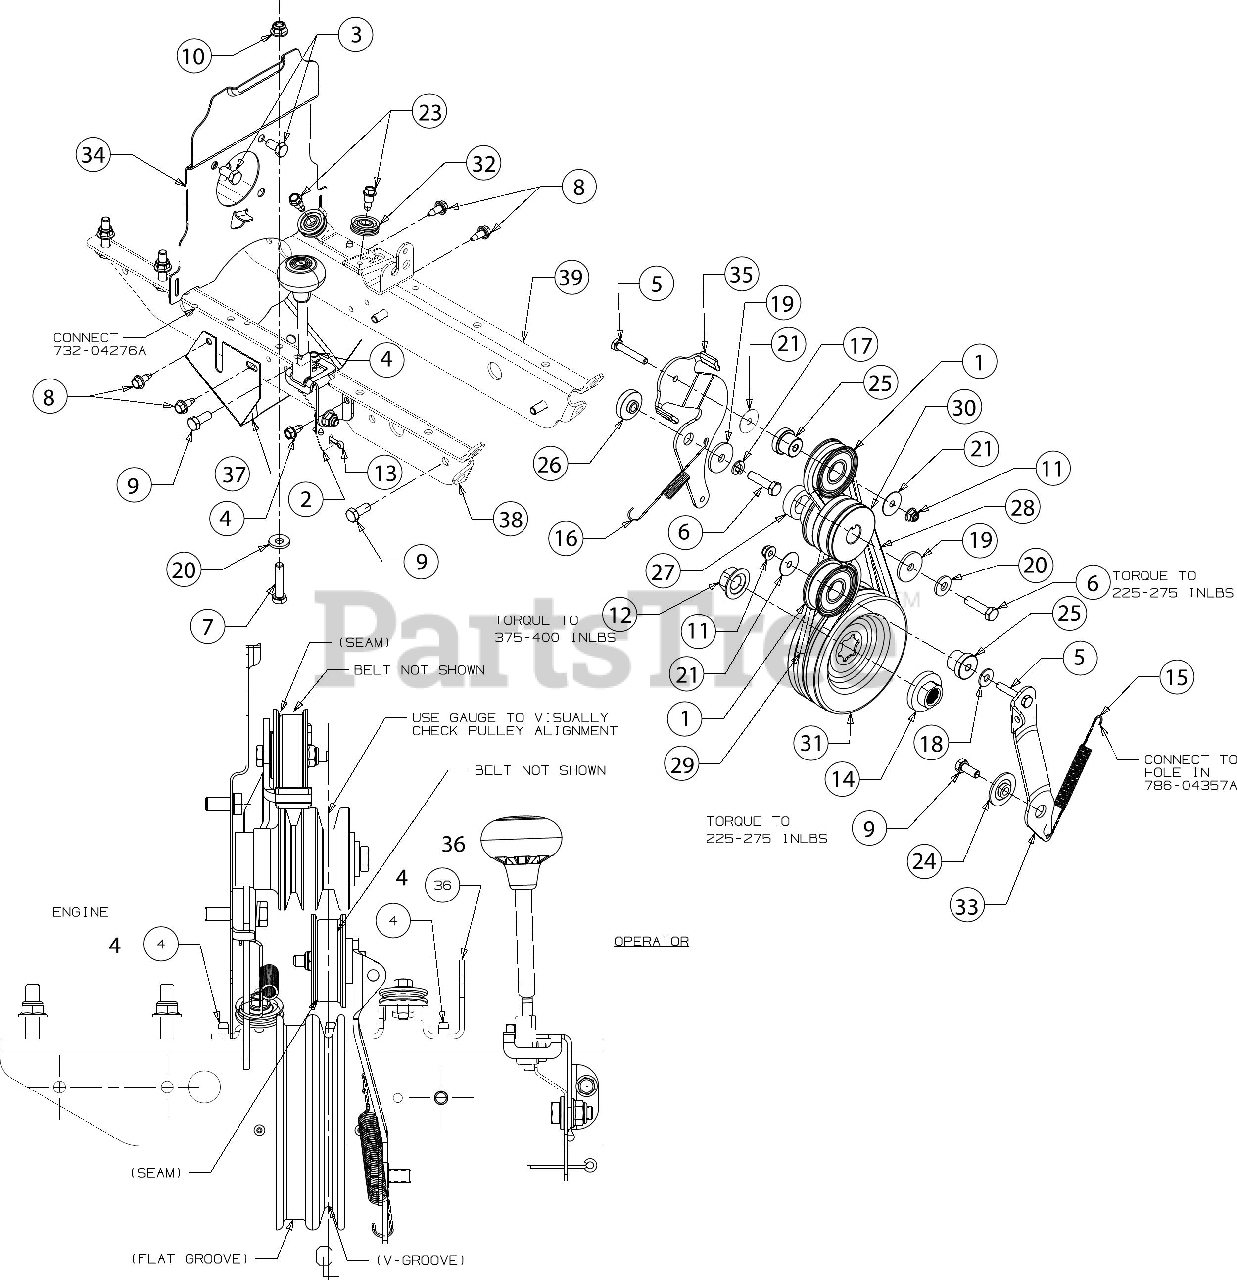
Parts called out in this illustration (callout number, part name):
1	IDLER PULLEY ASSEMBLY
1	BEARING SLEEVE
1	BALL BEARING
2	SHIFT KNOB
2	SCREW 1/4-20 X.500
2	WHEEL DRIVE PIVOT BRACKET
2	SCREW 5/16-18 x .750
2	FLANGE LOCK NUT 5/16-18
2	PIVOT BRACKET SPACER
2	WHEEL DRIVE MOUNT BRACKET
3	HEX SCREW 5/16-24 x .62
4	SCREW 1/4-20 X.500
5	SCREW 1/4-20 x 1.50 GR.5
6	SCREW 5/16-24 x 1.25 GR5
7	SCREW 5/16-18 x 1.5 LG
8	SCREW 1/4-14 x .625
9	SCREW 5/16-18 x .750
10	FLANGE LOCK NUT 5/16-18
11	FLANGE LOCK NUT
12	FLANGE NUT W/HUB
13	COTTER PIN-5/32 DIA
14	PULLEY HUB
15	RETURN SPRING
16	EXTENSION SPRING
17	LOCK WASHER 5/16
18	FLAT WASHER .28 ID x .74 OD x .063
19	WASHER-5/16 x 1.25X 1.27
20	BELLVILLE WASHER .827 x .331 x .098
21	FLAT WASHER
23	SHOULDER SCREW
24	PIVOT IDLER SPACER
25	SHOULDER SPACER
26	PIVOT IDLER SPACER
28	V-BELT FWD DRIVE 4L x 25.375
29	V-BELT REV DRIVE 3L x 29.125
30	ENGINE PULLEY
31	TRANSMISSION PULLEY
32	CABLE GUIDE ROLLER
33	FORWARD IDLER BRACKET
34	REVERSE IDLER BRACKET
35	REVERSE IDLER BRACKET
36	CABLE BRACKET ROLLER
37	PULLEY SHIELD
39	FRAME (RH) 400/460/480/VTT
